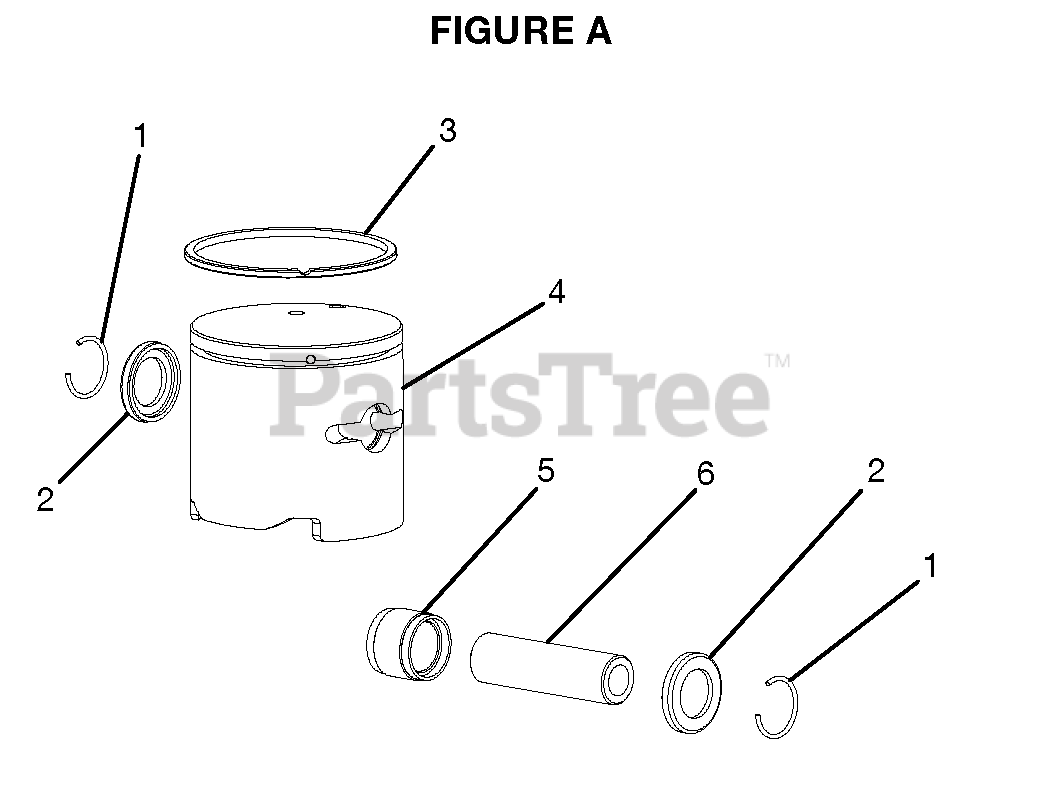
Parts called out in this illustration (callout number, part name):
1	WRIST PIN CLIP RING
3	PISTON RING
5	NEEDLE BEARING (ID 8 x 8.8)
6	WRIST PIN
